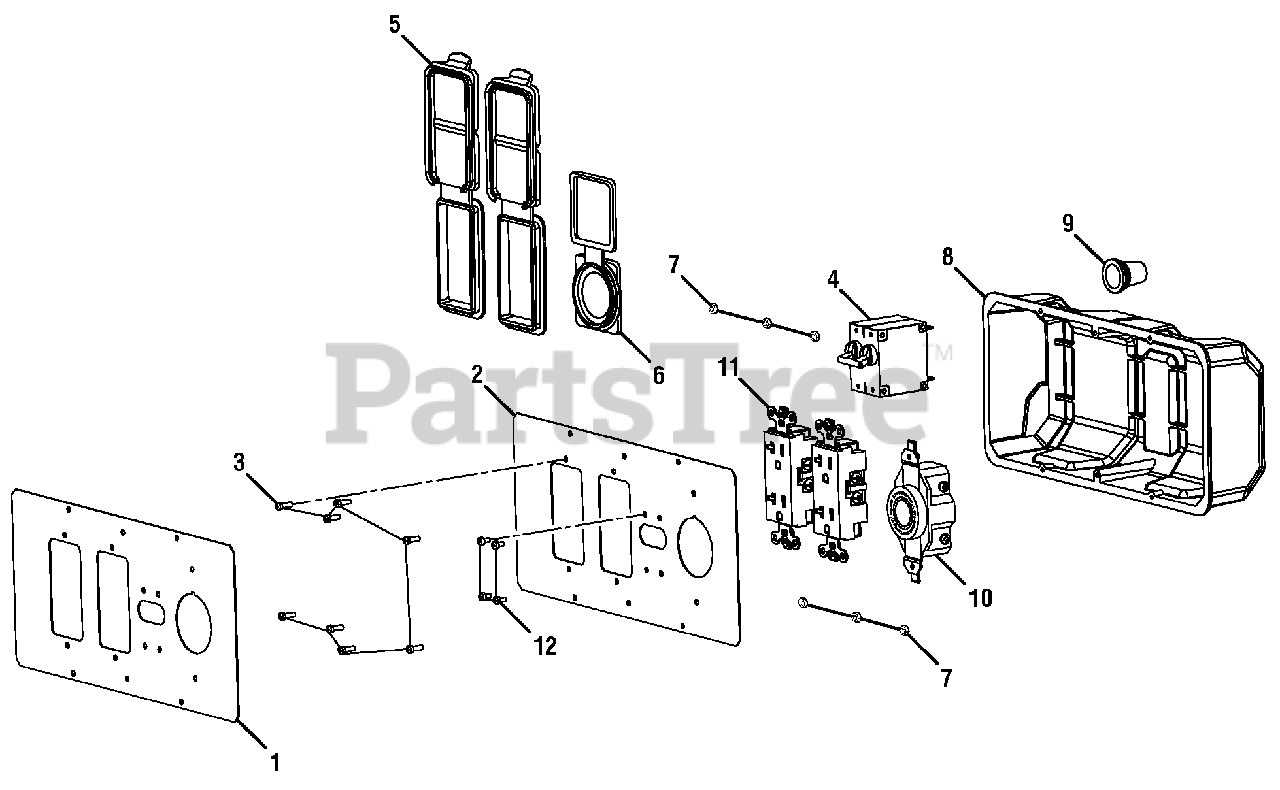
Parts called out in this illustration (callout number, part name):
1	Front Panel Label
2	Front Panel
3	Screw (#6-20 x .38 in.)
4	Circuit Breaker (20 Amp)
5	Outlet Cover (120 Volt)
6	Outlet Cover (240 Volt)
7	Lock Nut (#6- 32)
8	Control Box (Back Panel)
9	Rubber Sleeve
10	Twist Lock Receptacle (240 Volt)
11	Duplex Receptacle (120 Volt)
12	Screw (M3 x 6 mm)
